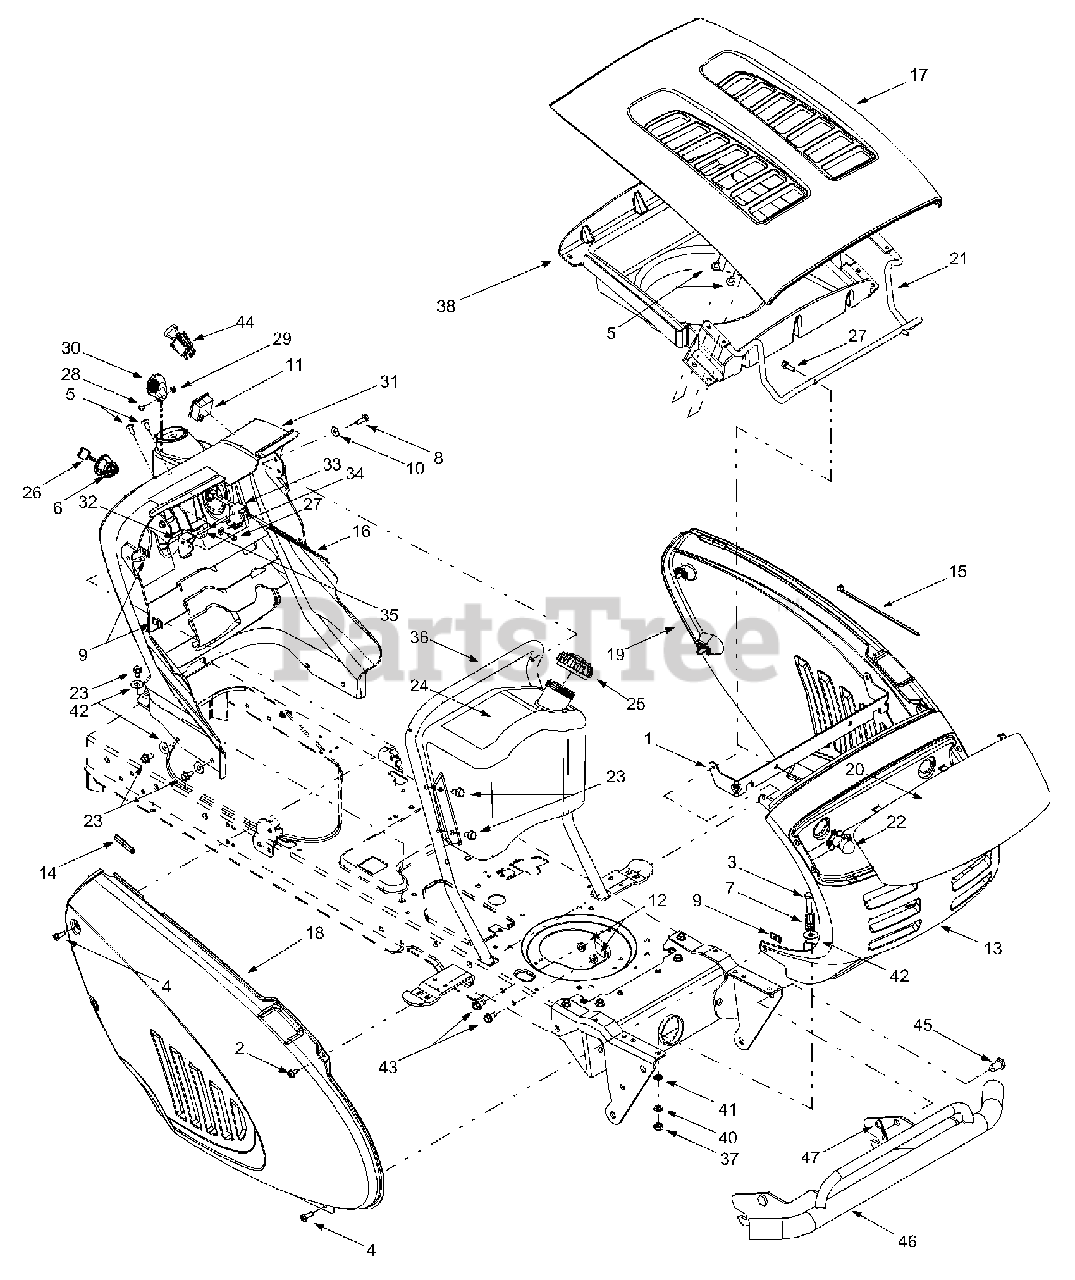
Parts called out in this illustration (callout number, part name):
2	Self-tapping Screw, 1/4-20 x .5
3	Hex Cap Screw, 5/16-18 x 1.25
4	Phillips Pan Screw, 1/4-20 x .75
5	Truss Phillips Screw, 1/4-20 x .625
6	Ignition Switch
7	Clamp, 9/16
8	Self-tapping Screw, 1/4-20 x .75
9	U-type Speed Nut, 1/4-20
10	Bell Washer, .265 x .75 x .062
11	Systems Indicator Monitor w/ Hour Meter
12	Hex Nut, 5/16-18
13	Grille (9-style)
14	Trim Strip, 4
15	Cable Tie, 3/16 x .05 x 7.4
16	Choke Knob/Cable (Models with any B&S Twin)
21	Hood Hinge Rod
22	Headlight Assembly
23	Self-tapping Screw, 5/16-18 x .625
24	Fuel Tank, Three Gallon
25	Fuel Cap
26	Ignition Key w/ plastic cover
27	Self-tapping Screw, 1/4-15 x .75
28	Truss Phillips Screw, #8-32 x .375
29	Hex Nut, #8-32
30	Throttle Control Knob
31	Dash Panel (Models w/ Electric PTO)
32	Cruise Control Button
33	Parking Brake Button
34	Flat Washer, 9/32 x 1/2 x 1/16
35	Brake/Cruise Pivot Rod
38	Hood Plenum (Models with Kohler)
40	Lock Washer, 5/16
41	Speed Nut, .3125
42	Flat Washer, .349 x 1.0 x .063
43	Screw, 5/16-18 x .875 (Grade 5)
44	Electric PTO Switch
45	Clevis Pin, .50 x .78
46	Bumper Assembly
47	Internal Cotter Pin
